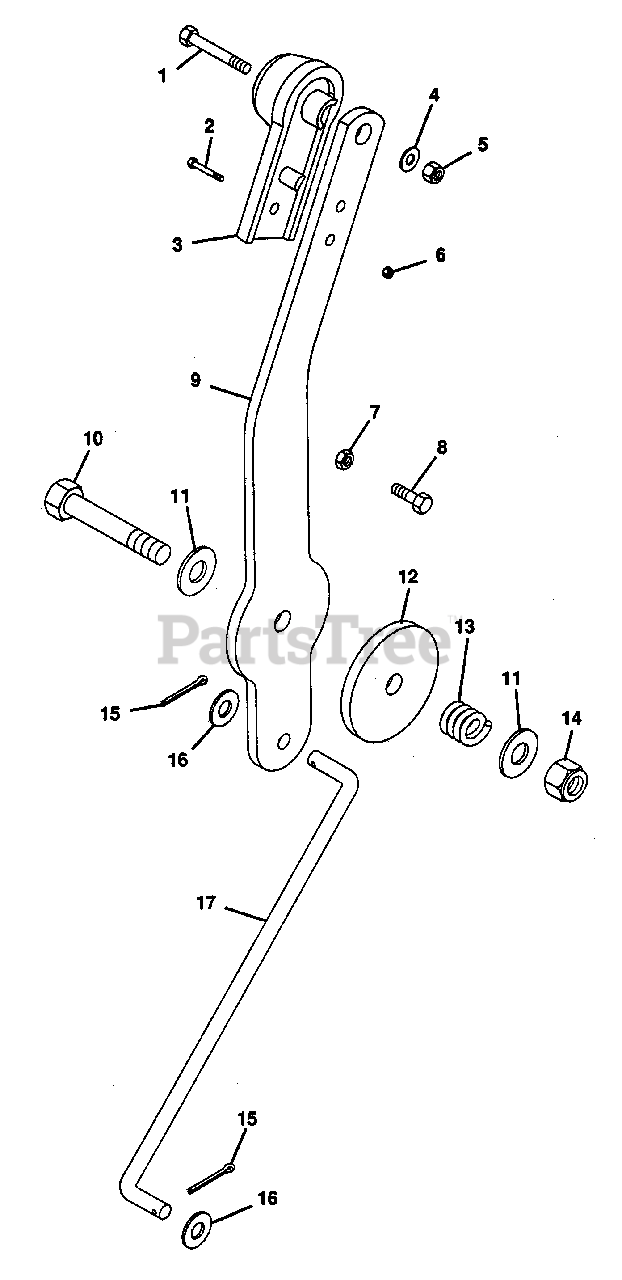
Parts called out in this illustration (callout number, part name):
1	Bolt, Hex 1/4-20x1.50
2	Screw, Mach. 6-32x.625 PHD
3	Knob, Handle Control
4	Washer, Flat .281x.625x.065
5	Nut, Lock 1/4-20
6	Nut, Mach. Lock 6-32
7	Nut, Hex 1/4-20
8	Bolt, Hex 1/4-20x.75
9	Lever, Speed Control
10	Bolt, Hex 1/2-13x2.50
11	Washer, Flat .531 x1.062x.095
12	Disc, Friction Material
13	Spring, Comp.1x.78x338 Lbrn
14	Nut, Lock 1/2-13
15	Pin, Cotter .094x1.00
16	Washer, Flat .406x.812x.065
17	Rod, Speed Control
